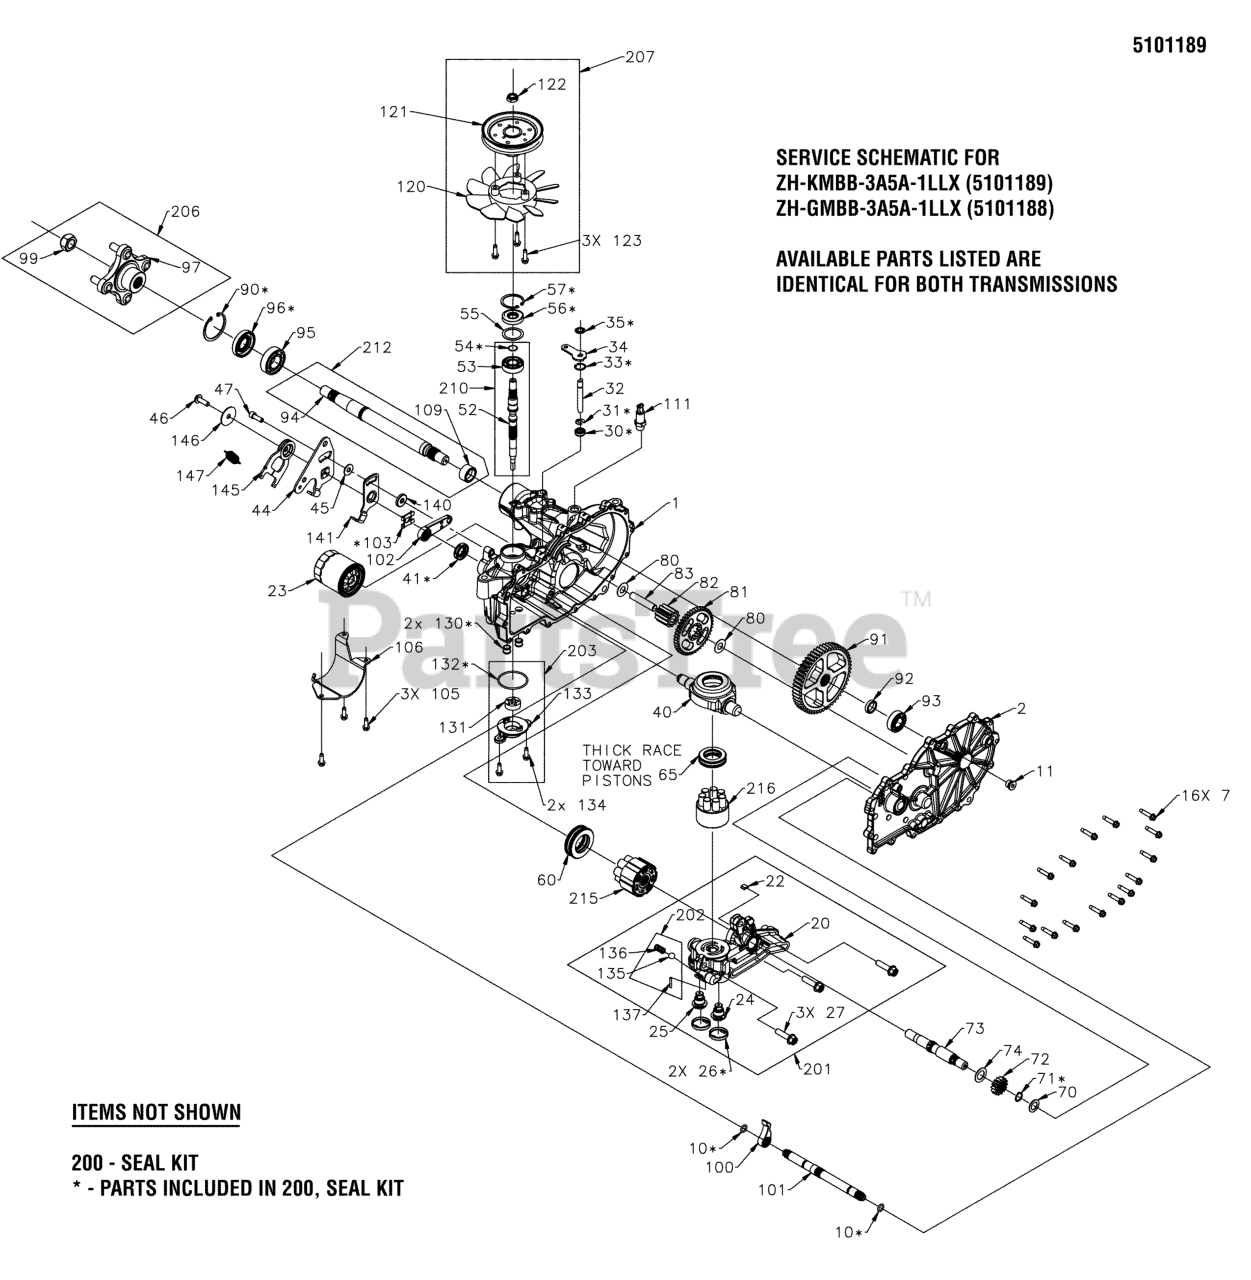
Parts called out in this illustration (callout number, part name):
23	FILTER, OIL, ZT2800
41	SEAL, CONTROL ARM, 18X32X7, #51140
56	SEAL, LIP, 17 X 40 X 7
57	RING, RET 2.06 INT
95	BEARING BALL, 1.0 X 52 X 15 OPEN 6205M
120	FAN, 7", 10 BLADE
121	*PULLEY, HYDRO-GEAR 50302
200	KIT SEAL
210	KIT, INPUT SHAFT
